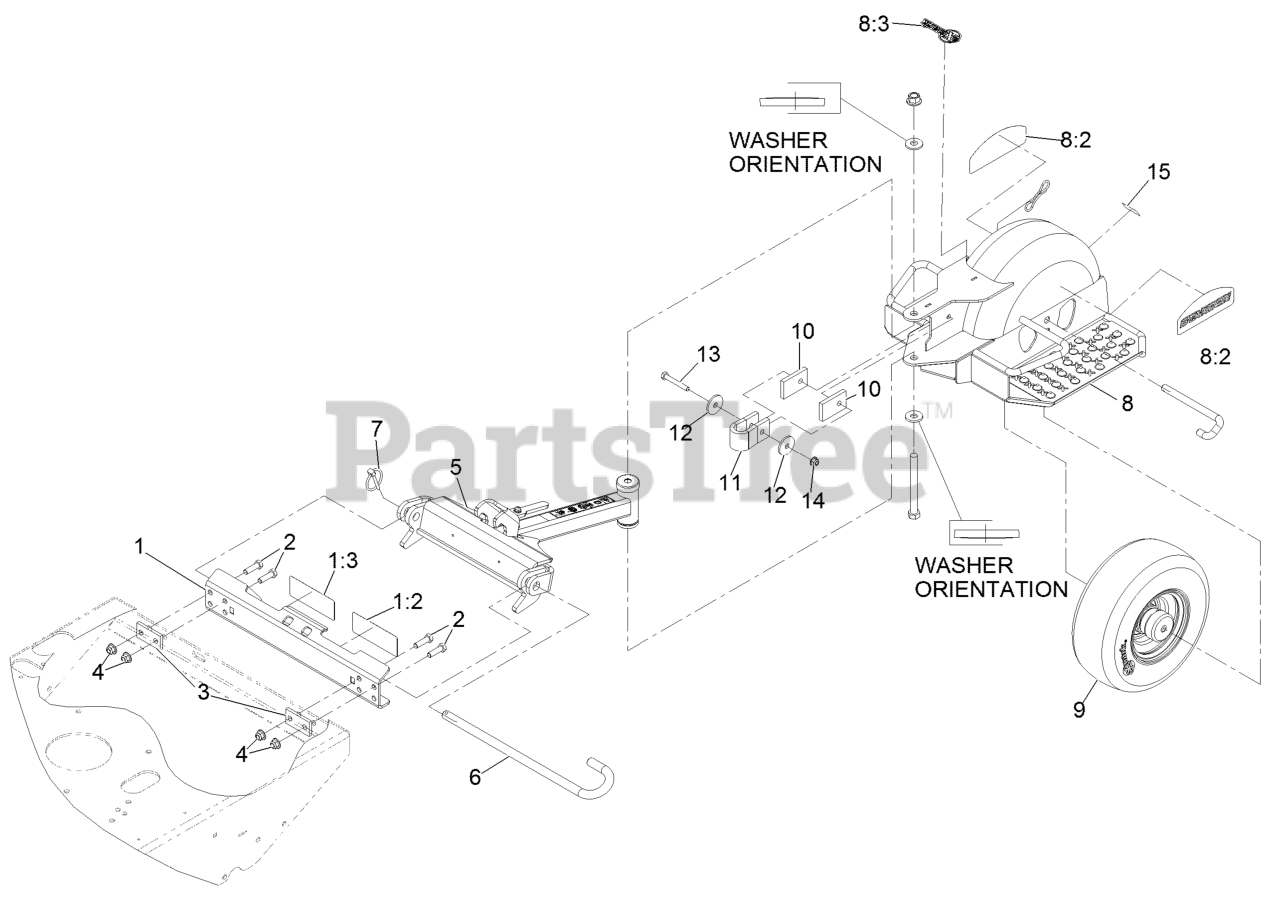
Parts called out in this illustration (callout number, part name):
1	ASM, MOUNT PLATE
1:2	DECAL-BELT DRIVE WARNING
1:3	DECAL-WARNING, SULKY
2	SCREW-HH
3	PLATE,BACK-UP (PLATED)
4	NUT-HF, NI
5	ASM, DRAW BAR
6	PIN, PIVOT
7	PIN-LYNCH
8	ASM-SULKY FRAME W/ DECALS
8:2	DECAL, STANDON
8:3	DECAL, EXMARK
9	ASM, WHEEL AND BEARINGS
10	PAD,STOP
13	SCREW-HH
14	NUT-HF, NI
15	Decal-Patent Ttco.Com
